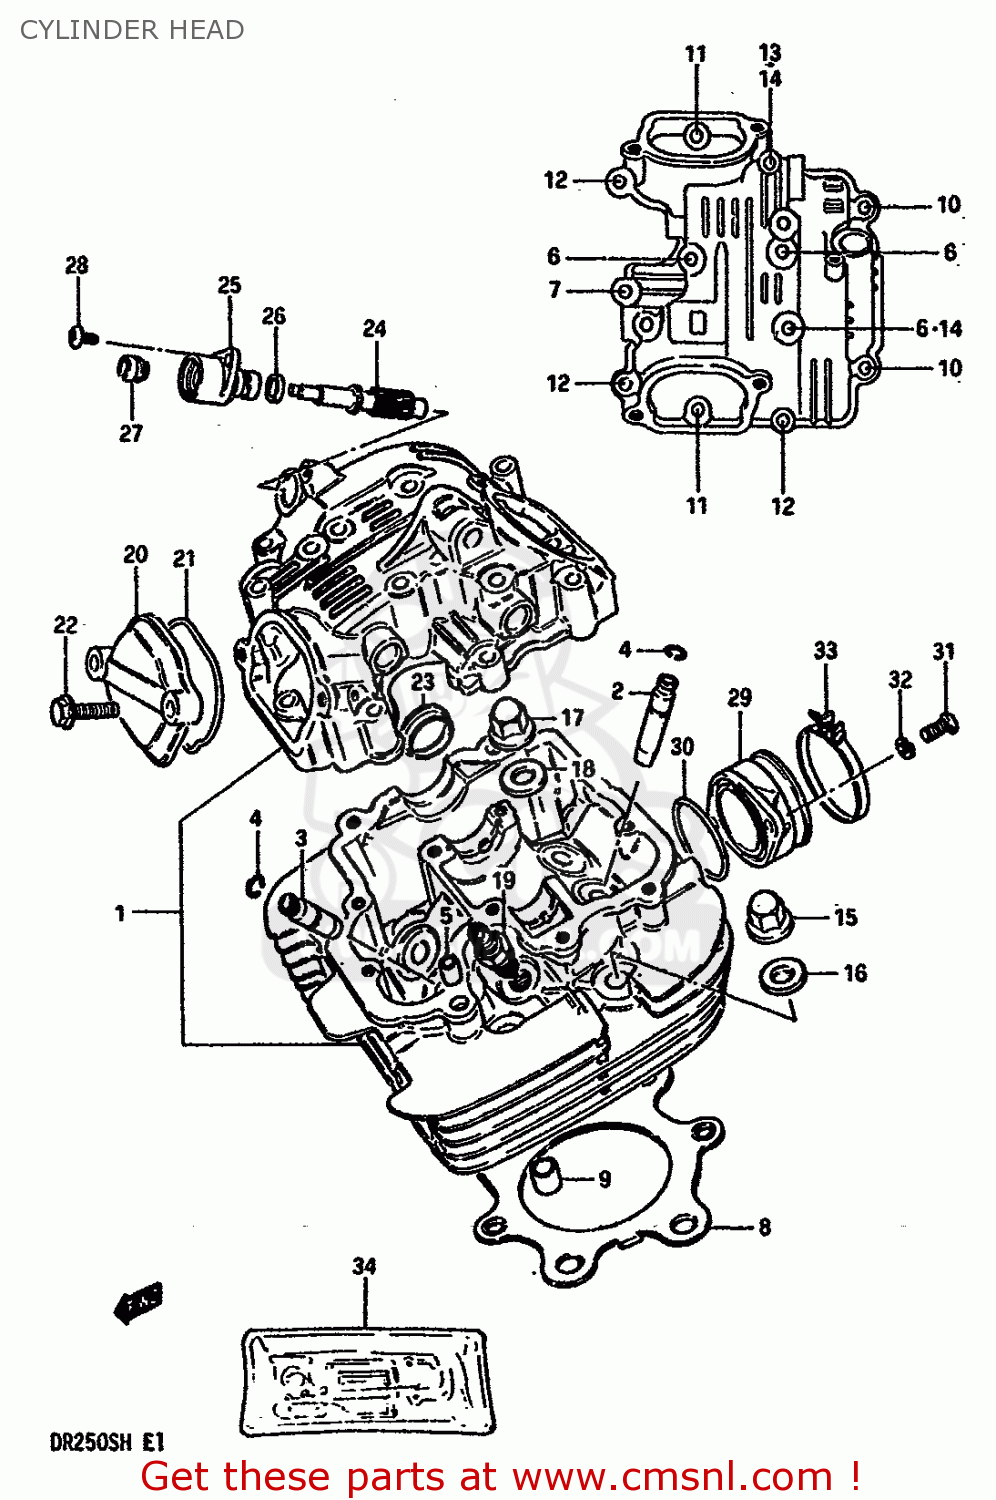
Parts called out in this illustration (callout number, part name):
1	HEAD,CYLINDER
2	GUIDE,INTAKE VALVE
3	GUIDE,VALVE
4	RING,SNAP
5	PIN(6.2X8X11)
6	BOLT ,6X60
7	BOLT 6X30
8	GASKET,CYLINDER HEAD (NAS)
9	PIN
10	BOLT
11	BOLT 6X30
12	BOLT (6X45)
13	BOLT ,6X60
14	GASKET(5.8X13X1.2) (NAS)
15	NUT
16	WASHER (10.5X22X2.3)
17	NUT
18	GASKET(10.5X22X2) (NAS)
19	SPARK PLUG D8EA
20	CAP,INSPECTION
21	O RING(D:2.4,ID:23)
22	BOLT
23	PLUG(OD:30)
24	GEAR,TACHOMETER DRIVEN
25	SLEEVE,TACHOMETER DRIVE GEAR
26	SEAL,TACHOMETER DRIVEN
27	SEAL,OIL(5X12X8)
28	SCREW(5X12)
29	PIPE,INTAKE
30	O-RING (D:2.4 ID:39.7)
31	SCREW
32	WASHER,LOCK
33	CLAMP
34	GASKET SET (MCA)
